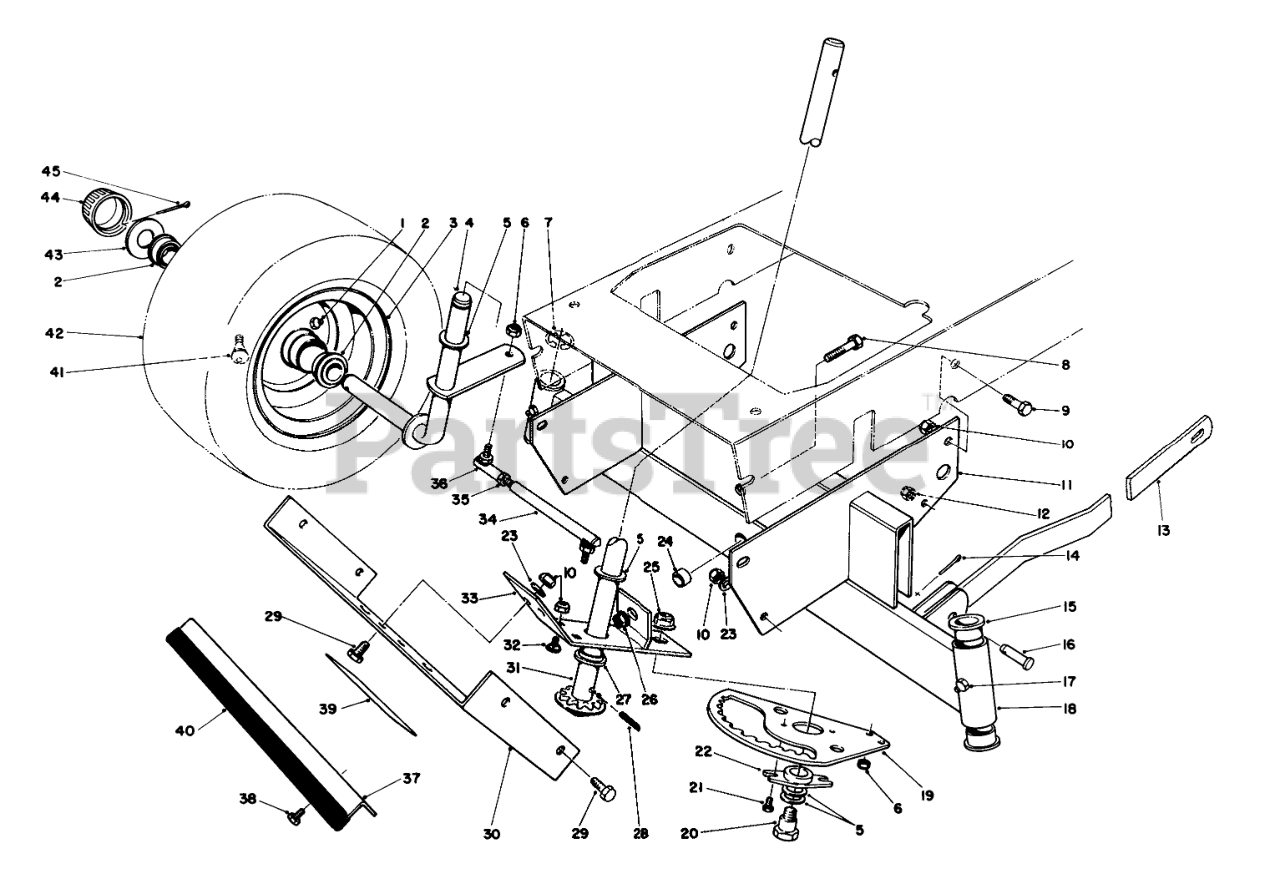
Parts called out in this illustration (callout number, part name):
1	FITTING-GREASE
2	Bearing
4	Spindle RH
5	WASHER-THRUST
6	NUT-LOCK
7	E-RING
8	SCREW-HH
9	SCREW-HH
10	NUT-LOCK, NI
11	Support
12	NUT-LOCK, CONE
13	Arm-Suspension, Front
14	PIN-COTTER
15	BEARING-FLANGE
16	PIN-CLEVIS
17	GREASE FITTING
18	Axle-Front (Incl. Ref. #15 & 17)
19	STEERING RACK B
21	SCREW
22	BUSHING-SECTOR
23	WASHER-PLAIN
24	SPACER-AXLE, FRONT
25	NUT-HF
26	NUT-HF
27	BEARING-FLANGE
28	PIN-ROLL, SLOTTED
29	SCREW-HH
30	Cover-Front
31	STRG SHAFT WA
32	SCREW-CARR
33	Bracket-Steering Rack (Incl. Ref. #27)
34	Tie Rod-Steering (Incl. Ref. #35 & 36)
35	NUT-JAM
36	JOINT-BALL
37	FRONT GUARD R
38	SCREW-HWHTF
39	Decal-Warning
40	TRIM-FRONT GUARD
41	STEM-VALVE
42	TIRE,PNEU.11X4.00X5
43	WASHER-PLAIN
44	CAP-HUB
45	PIN-COTTER
